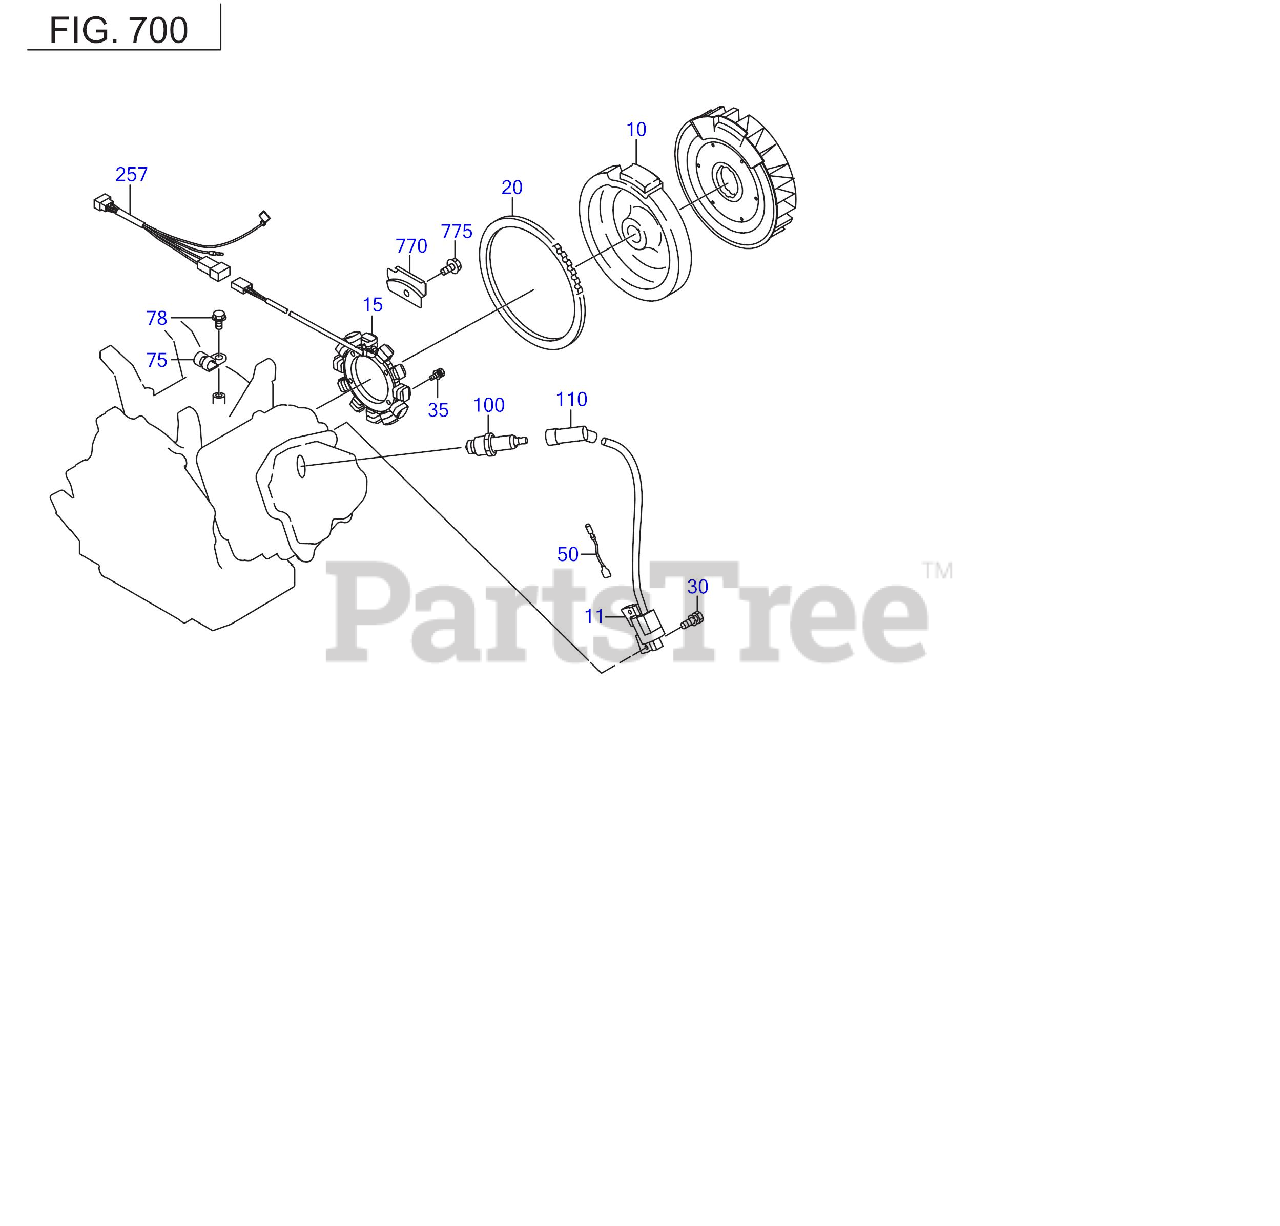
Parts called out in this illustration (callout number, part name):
11	IGNITION COIL CP
15	CHARGE COIL CP
30	BOLT AND WASHER AY
35	SCREW AND WASHER AY
110	SPARK PLUG CAP
257	WIRE HARNESS CP
